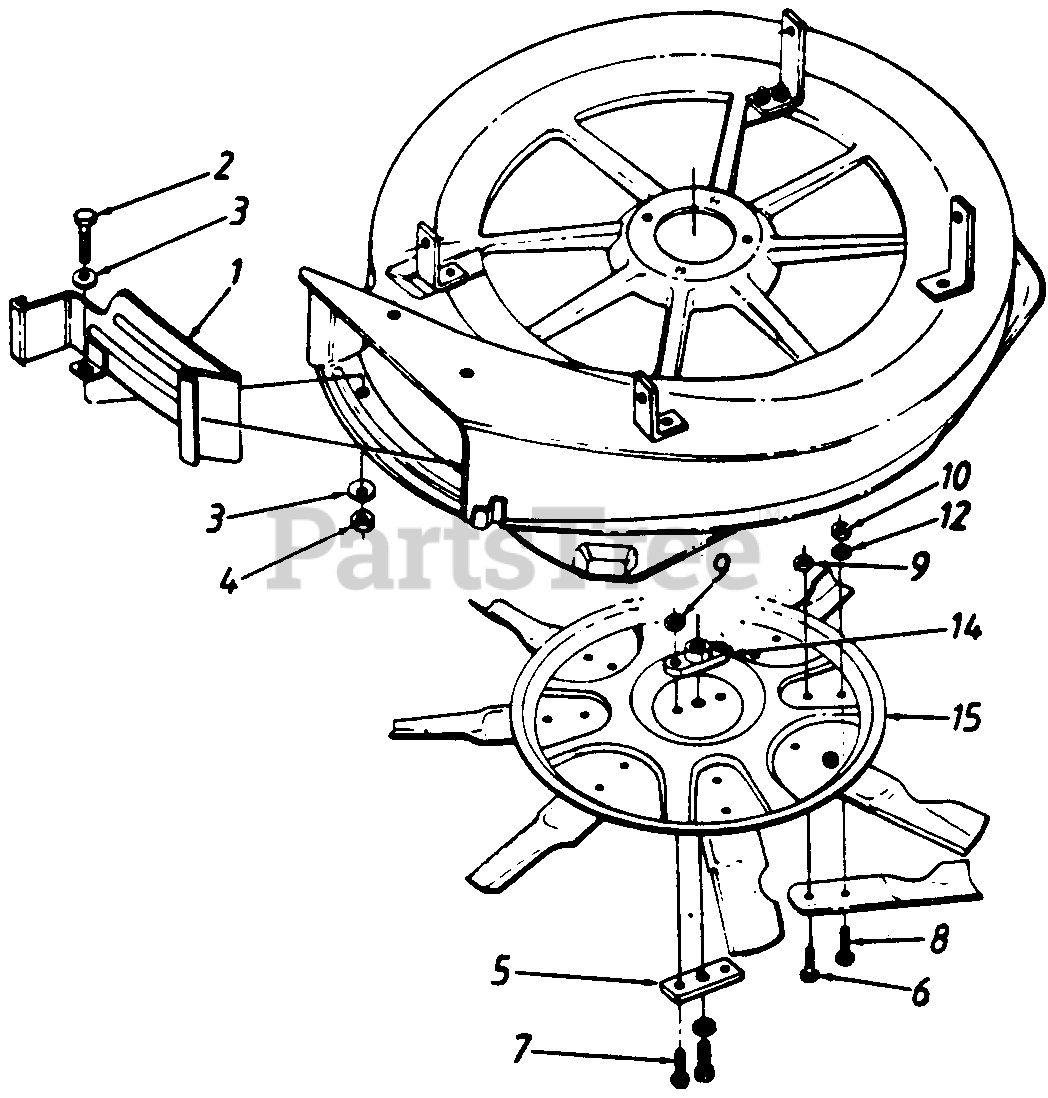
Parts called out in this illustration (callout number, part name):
1	Mulching Baffle Ass'y.
2	Hex Bolt 5/16-18 x .5
3	Bell-Wash. .825" l.D.
4	Hex L-Nut 5/16-18 Thd.
7	Hex Bolt 5/16-24 x 1.25" Lg. (Gr. 5)
8	Hex Bolt 3/8-24 x .88" Lg.
9	Hex L-Nut 5/16-24 Thd.
10	Hex L-Nut 3/8-24 Thd. (Gr. 5)
12	Fl-Wash. .406" l.D. x .75n
14	Blade Adapter
15	30 Mulching Blade Disc
